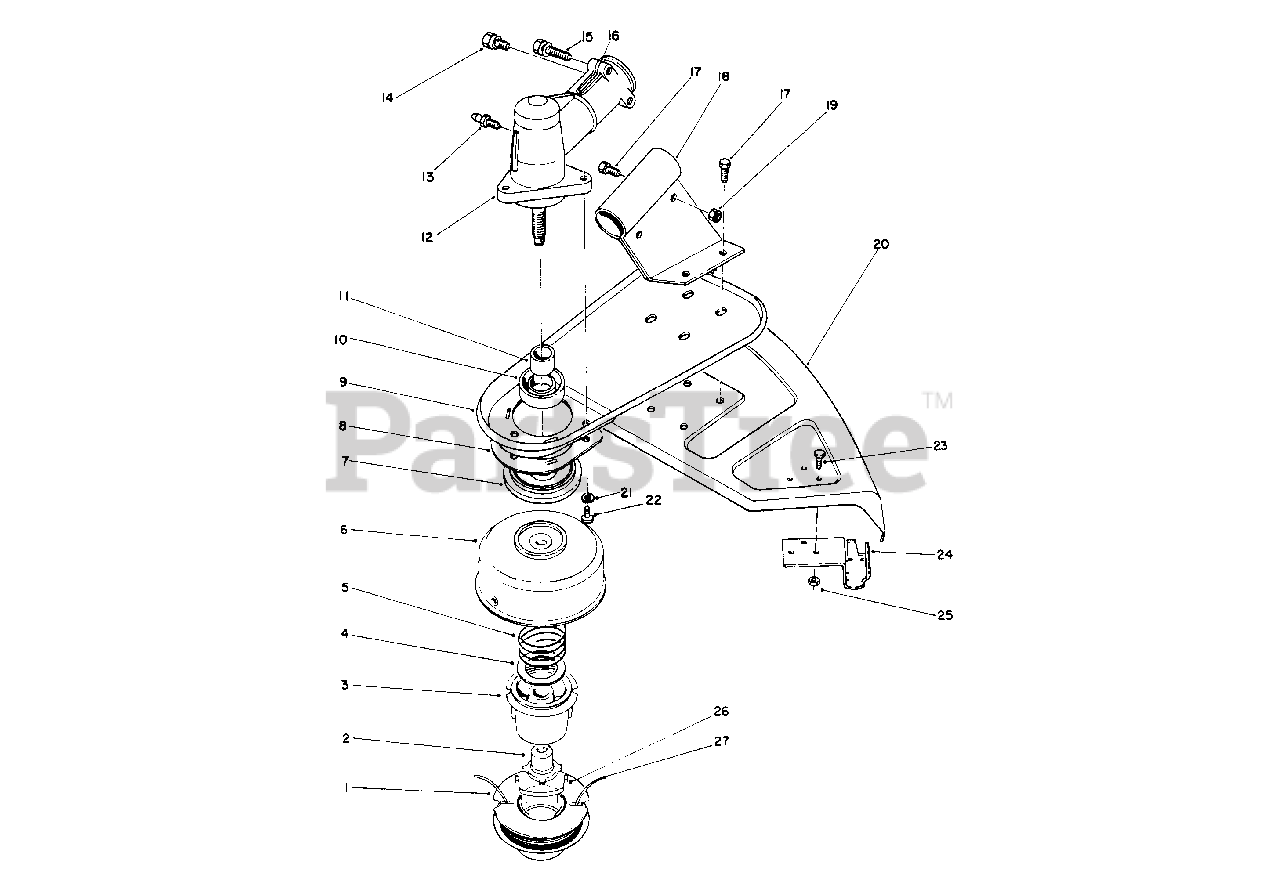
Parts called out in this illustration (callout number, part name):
1	Spool-Prewound .08 Dia .38' (Incl. Ref. #26)
2	Driver L.H.
3	Core-Spool
6	Drum w/Eyelets
7	Cap-Dust
8	Guard-Grass Wrap
9	Support-Shield
10	Seal-Oil
11	Sleeve-Spline
12	Gear Box Assembly (Incl. Ref. #10, 11, & 13-16)
13	Fitting-Grease
14	Screw-Hex. Hd.
15	Screw-Hex. Hd.
16	Washer-Flat
17	Screw-Hex. Hd.
18	Bracket-Shield
19	Nut-Lock
20	Shield-Grass
21	Washer-Lock
22	Screw-Guard
